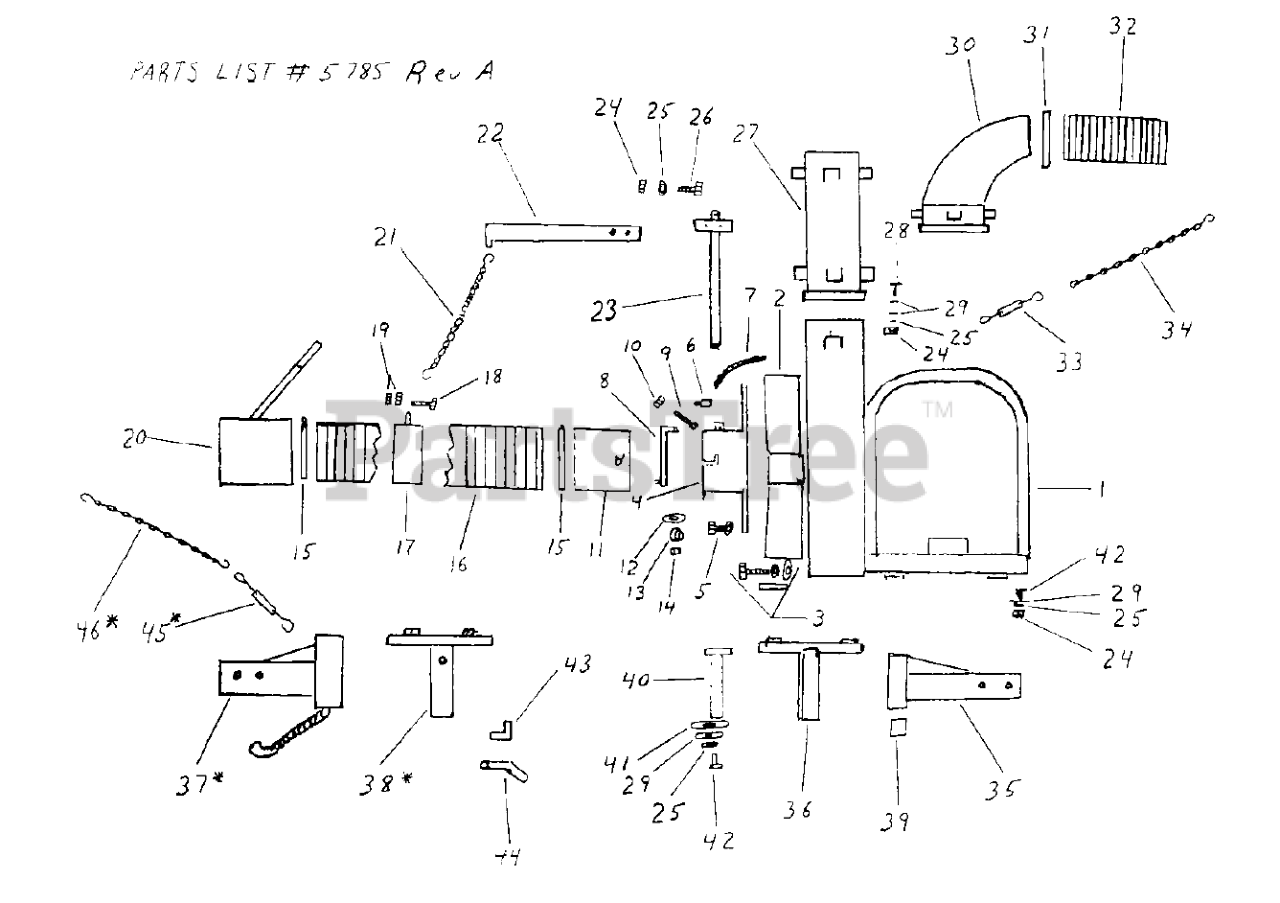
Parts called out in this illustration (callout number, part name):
1	Motor base & housing
3	7/16-20 x 2 impeller bolt, washers & key
4	Intake flange - 10
5	5/16 x 3/4 hex bolt & lock washer
6	Safety cutoff switch
7	Safety switch wiring harness
8	Intake flange safety cover - 10
9	1/2 x 2-1/2 hex bolt
10	1/2 lock nut
11	Quick-release hose adaptor - 10
12	5/16 fender washer
13	5/16 plastic knob nut
14	5/16 lock nut
15	8 hose clamp
15	10 hose clamp
16	10 x 10’ intake hose
17	10 support band
18	5/16 x 3-1/2 hex bolt
19	5/16 nut
20	Intake nozzle - 10
21	Boom chain
22	Upper boom support
23	Lower boom support
25	1/2 lockwasher
26	1/2 x 1 hex bolt
27	Discharge stack
28	1/2 x 4-1/2 hex bolt
29	1/2 flatwasher
30	Discharge elbow
31	7 squeeze ring
32	7 x 30 metal discharge hose
33	3/8 x 7-1/2 turnbuckle
34	Upper body support chain
35	Standard swing arm - vehicle side
36	Standard swing arm - unit side
37	* X-long swing arm - vehicle side
38	* X-long swing arm - unit side
39	Swing arm bushing
40	Swing arm pivot pin
41	5/8 flatwasher
42	1/2 x 1-1/4 hex bolt
43	Swing arm locking bracket
44	5/8 - 11 handle nut
45	* 3/8 x 7-1/2 turnbuckle
46	* Boom chain (secondary safety Chain for x-long swing arm)
